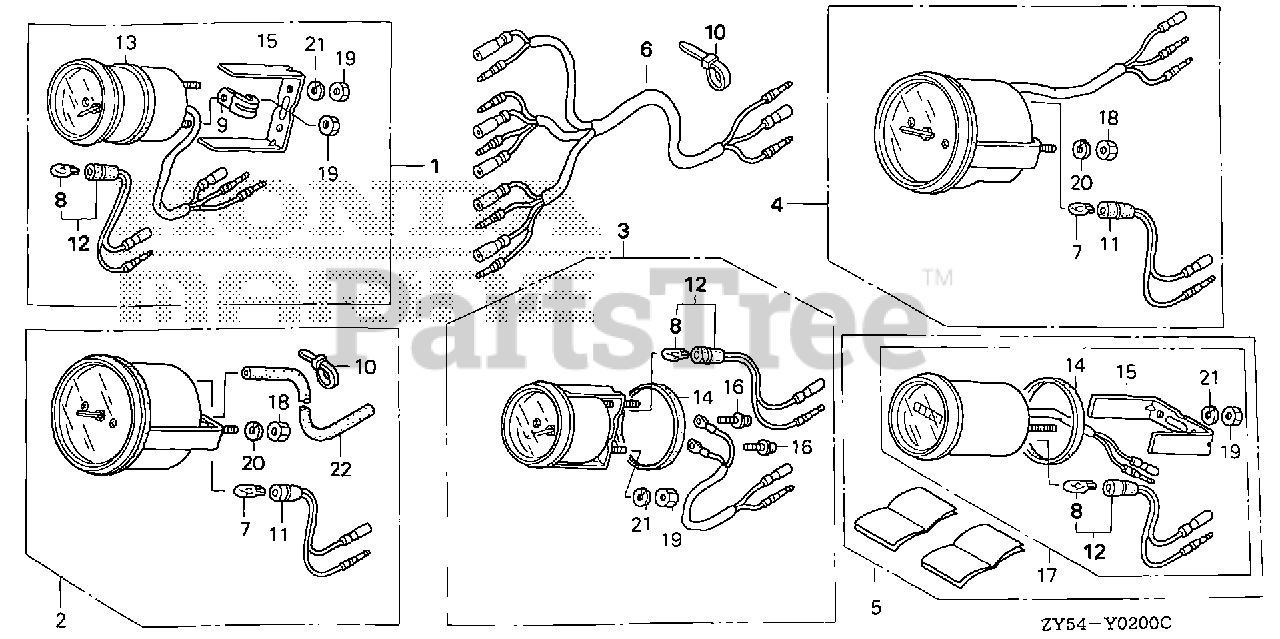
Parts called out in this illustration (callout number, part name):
1	METER KIT, TRIM (WHITE)
1	METER KIT, TRIM (B) (BLACK)
2	SPEEDOMETER KIT (WHITE)
2	SPEEDOMETER KIT *NHA85* (B) (BLACK)
3	METER KIT, VOLT (WHITE)
3	METER KIT, VOLT *NHA85* (B) (BLACK)
4	METER KIT, TACHO
4	METER KIT, TACHO (B)
5	METER KIT, HOUR (WHITE) (NA USE ALT:39700-ZW5-000ZA)
5	METER KIT, HOUR (B) (NA USE ALT:39700-ZW5-000ZA)
6	HARNESS ASSY., METER (B)
7	BULB, WEDGE BASE (T10) (12V 1.7W) (STANLEY)
8	BULB, WEDGE BASE (12V1.7W) (TOSHIBA)
9	CLAMP
10	BAND, SELF-LOCK
11	SOCKET
12	SOCKET
13	GASKET (TO 1015209) (FROM 1015210)
14	GASKET
15	BRACKET (TO 1015209) (FROM 1015210)
16	SCREW-WASHER (3X22)
17	METER ASSY., HOUR
17	METER ASSY., HOUR (B)
18	NUT, HEX. (5MM)
19	NUT, HEX. (4MM)
20	WASHER, SPRING (5MM)
21	WASHER, SPRING (4MM)
22	TUBE, SPEED METER (4X7X8000)
